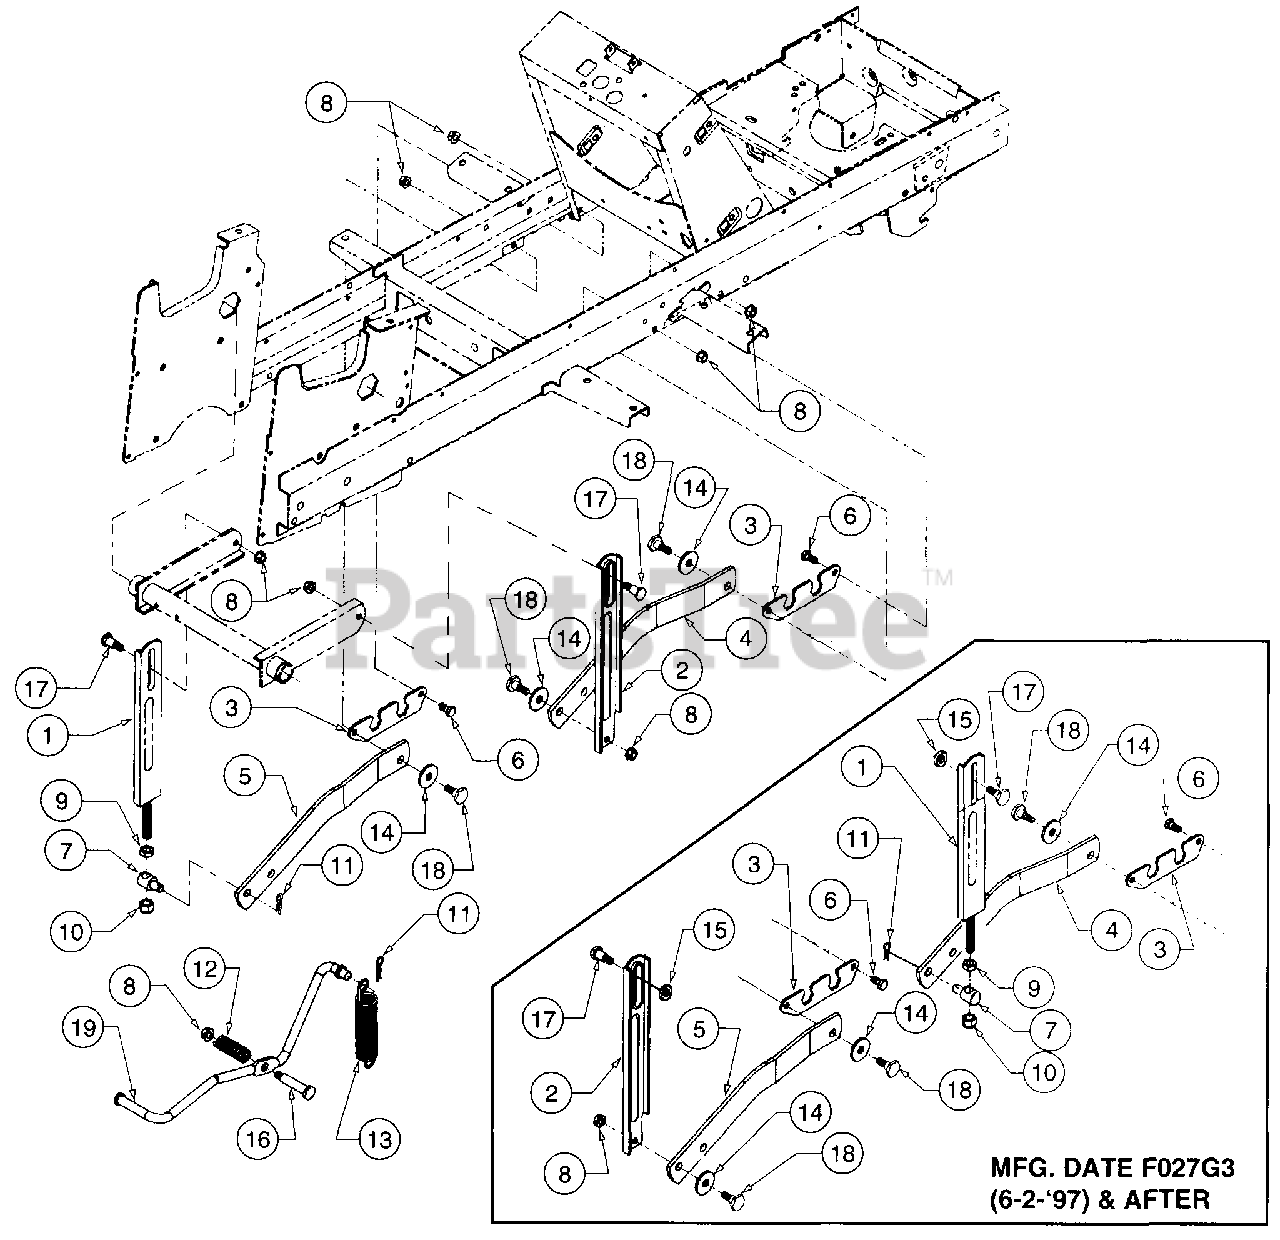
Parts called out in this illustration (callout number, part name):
7	Ferrule, Adjustment
8	Nut, Hex Flange Lock, 3/16
9	Nut, Hex Jam, 1/2-13 GR5
10	Nut, Hex Insert Lock, 1/2-13
11	Pin, Internal Cotter
12	Spring, Compression, .63 ID x 2.0
13	Spring, Extension, 1.0 OD x 6.42 Lg
14	Washer, Flat, .50 x 1.5 x .15
15	Washer, Flat, .531 x .875 x .15
16	Bolt, Shoulder
17	Bolt, Shoulder
18	Bolt, Shoulder
19	Rod, RH Lift Assist
